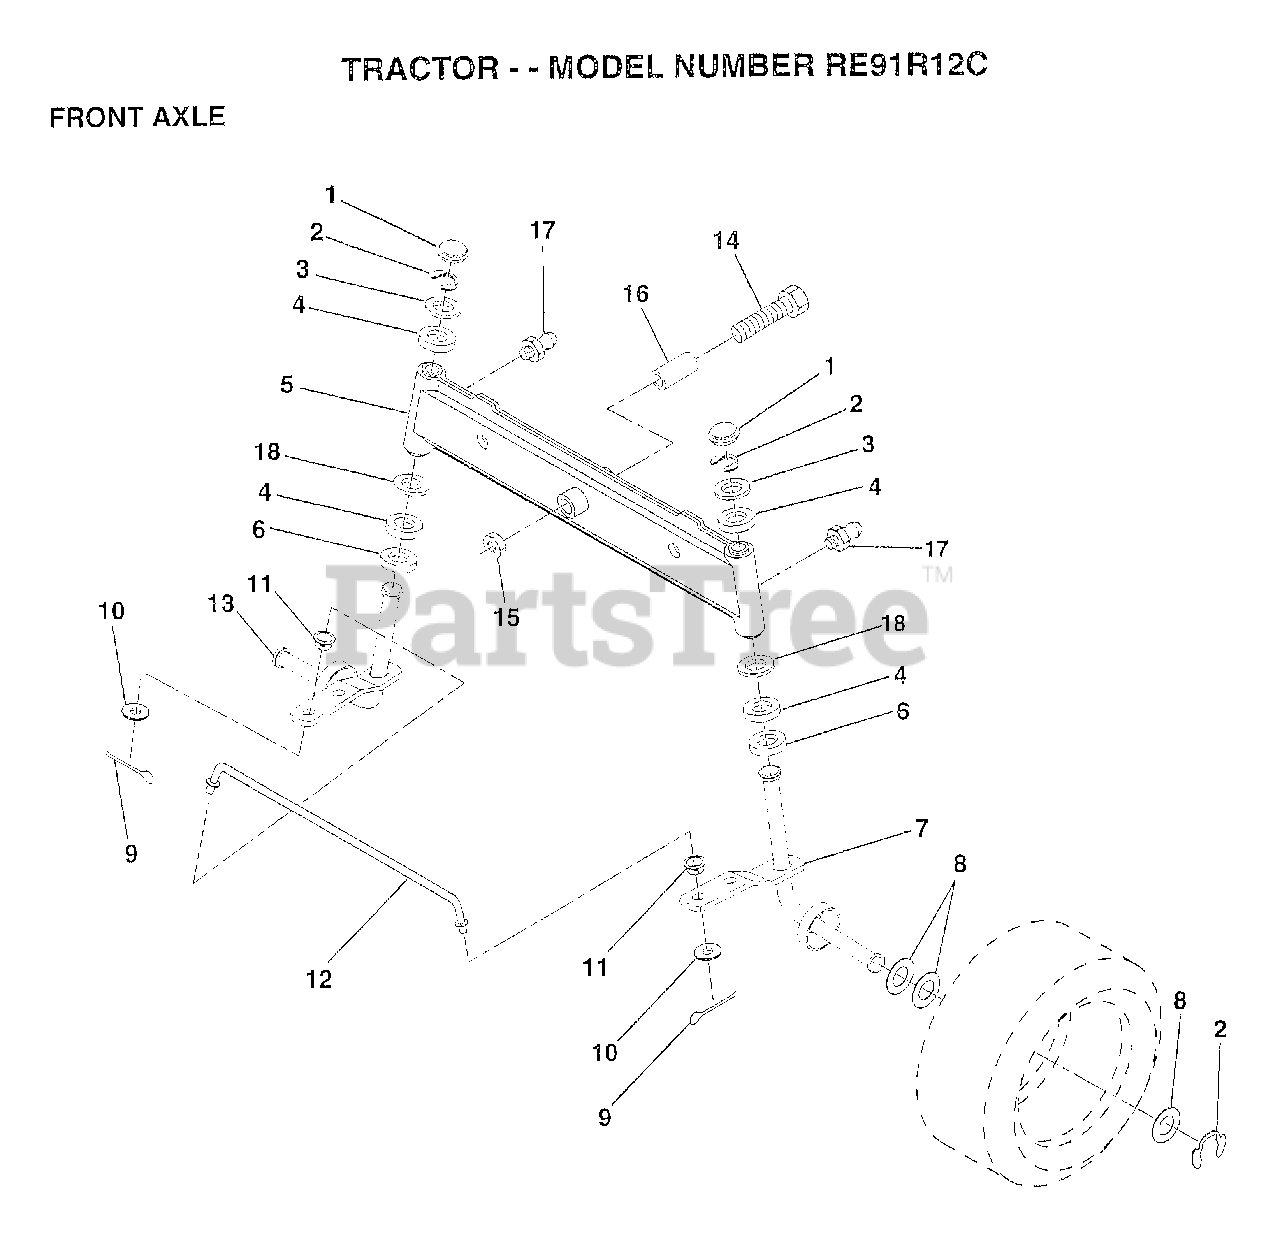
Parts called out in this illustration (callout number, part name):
1	CAP
2	RING
3	WASHER
4	COL. SRTG. BEAR.
5	AXLE ASM FRONT
6	WASHER .T
7	SPINDLE.ASSY.RH
8	WASHER
9	COTTER PIN
10	WASHER
11	BUSHING.DRAGLINK
12	TIE ROD
13	SPINDLE.ASSY.LH
14	BOLT HEX 5/8-11
15	"NUT-LOC,FLANGE LT"
16	BEARING
17	ZERK M
18	WASHER
